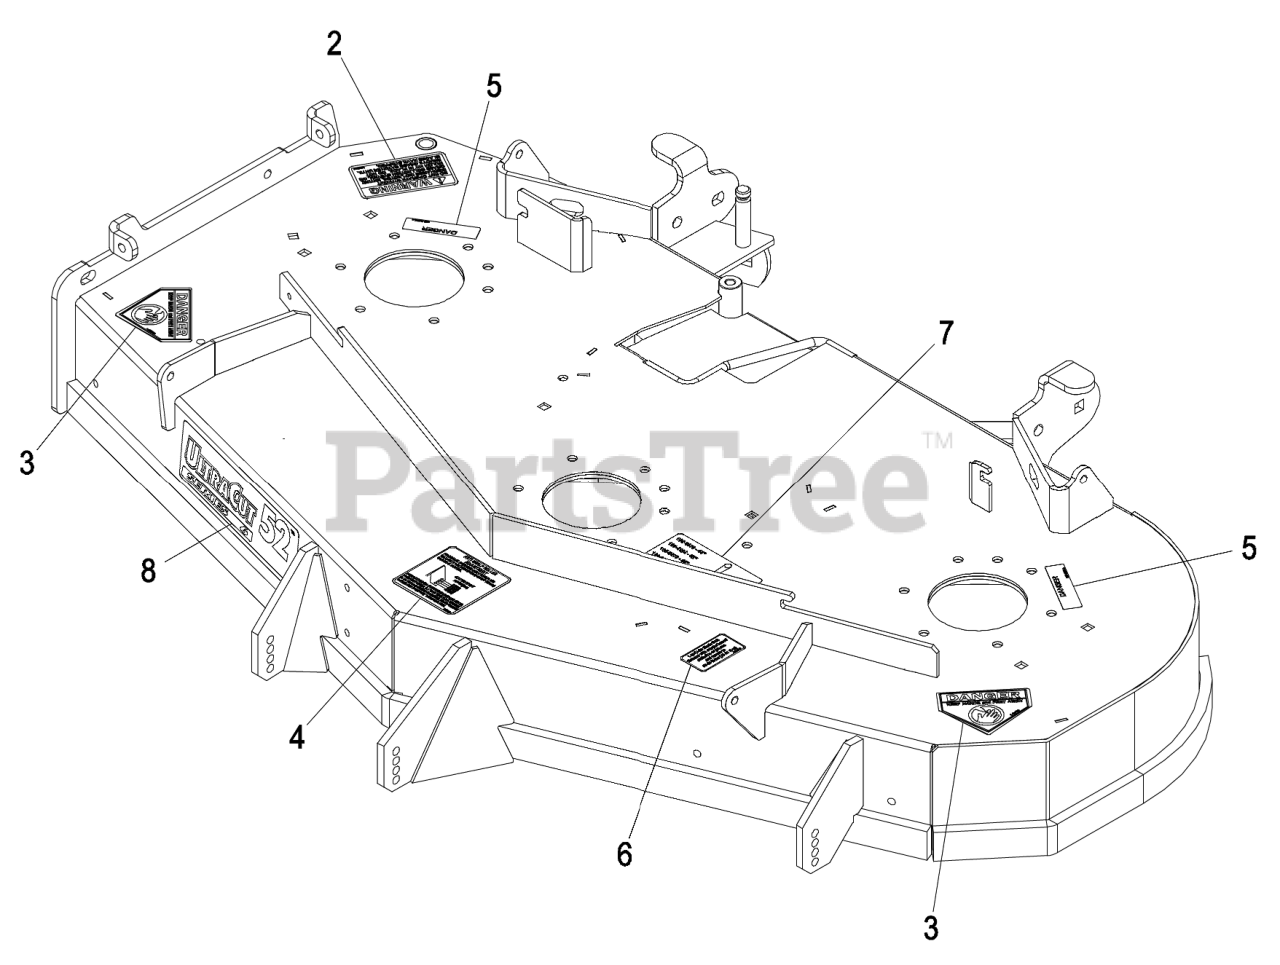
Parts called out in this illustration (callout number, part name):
2	DECAL-WARNING, DISCHARGE
3	DECAL-DANGER
4	DECAL,ANTISCALP
5	DECAL-COVER, MISSING
6	DECAL,BOLT TORQUE
7	DECAL,BELT ROUTING
8	DECAL,ULTRACUT 52 SERIES
